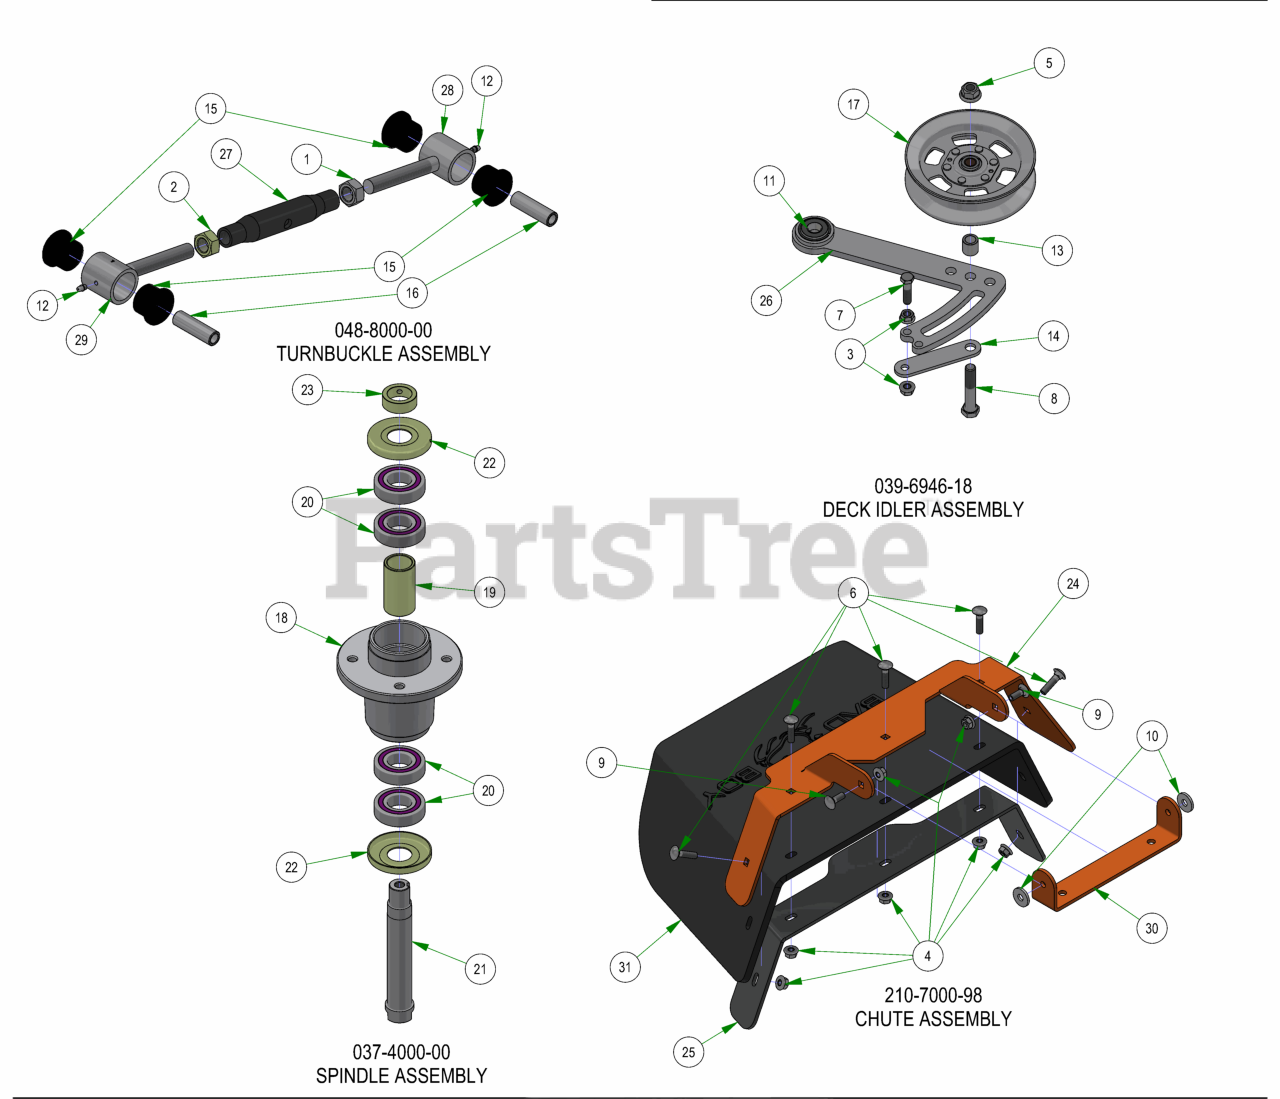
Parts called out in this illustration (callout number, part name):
1	Hex Nut M20-2.5
2	Hex Nut M20-2.5 Left Hand Threads Gold Plated
3	3/8-16 HEX SERRATED FLANGE NUT HARD/ZINC
4	5/16-18 NYLON INSERT FLANGE LOCKNUT ZINC
5	1/2-13 NYLON INSERT FLANGE LOCKNUT ZINC
6	5/16-18 X 1-1/4 CARRIAGE BOLT ZINC
7	3/8-16 X 1-1/2 HEX CAP SCREW (GR.5) ZINC
8	1/2-13 X 2-3/4 HEX CAP SCREW (GR.5) ZINC
9	5/16-18 X 7/8 CARRIAGE BOLT ZINC
10	.360 ID X .983 OD X .120 THICK FLAT WASHER NYLON
11	Ball Bearing w/Retainer, 99502H-NR, .625 Bore x 1.375 OD x .4375 Width
12	1/4-28 Grease Fitting
13	.51 ID X .75 OD X .75 LGTH SOLID SPACER ZINC
14	Belt Tensioner Retainer Plate
15	Polyeurethane Bushing
17	5" Idler Pully
18	4000 Series Spindle Housing
19	4000 Series Spindle Spacer
20	Bearing - 6206
21	Spindle Shaft
22	Spindle Dust Cap
23	Locking Collar w/ 1/4"-20 Set Screw
24	2019 Upper Chute Bracket
25	2019 Lower Chute Bracket
26	2019 Deck Belt Tensioner
27	2024 Turnbuckle Body
28	Turnbuckle End Right-Handed Thread
29	Turnbuckle End Left-Handed Thread
30	2019 Chute Hanger
31	2019 Belted Chute with Logo
